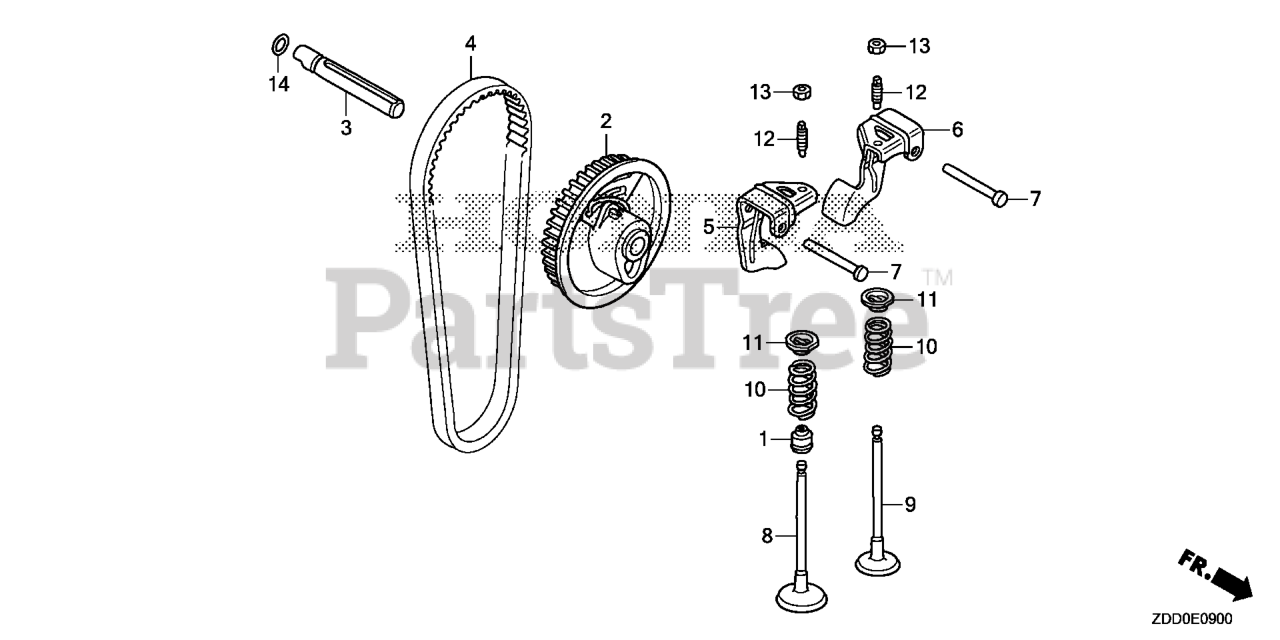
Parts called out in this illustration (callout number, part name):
1	SEAL, VALVE STEM
2	PULLEY, CAMSHAFT
3	SHAFT, CAM PULLEY
4	BELT, TIMING (61YU7 G-200)
5	ARM, IN. VALVE ROCKER
6	ARM, EX. VALVE ROCKER
7	SHAFT, ROCKER ARM
8	VALVE, IN.
9	VALVE, EX.
10	SPRING, VALVE
11	RETAINER, VALVE SPRING
12	SCREW, TAPPET ADJ.
13	NUT, TAPPET ADJ.
14	O-RING (6.8X1.9) (ARAI)
